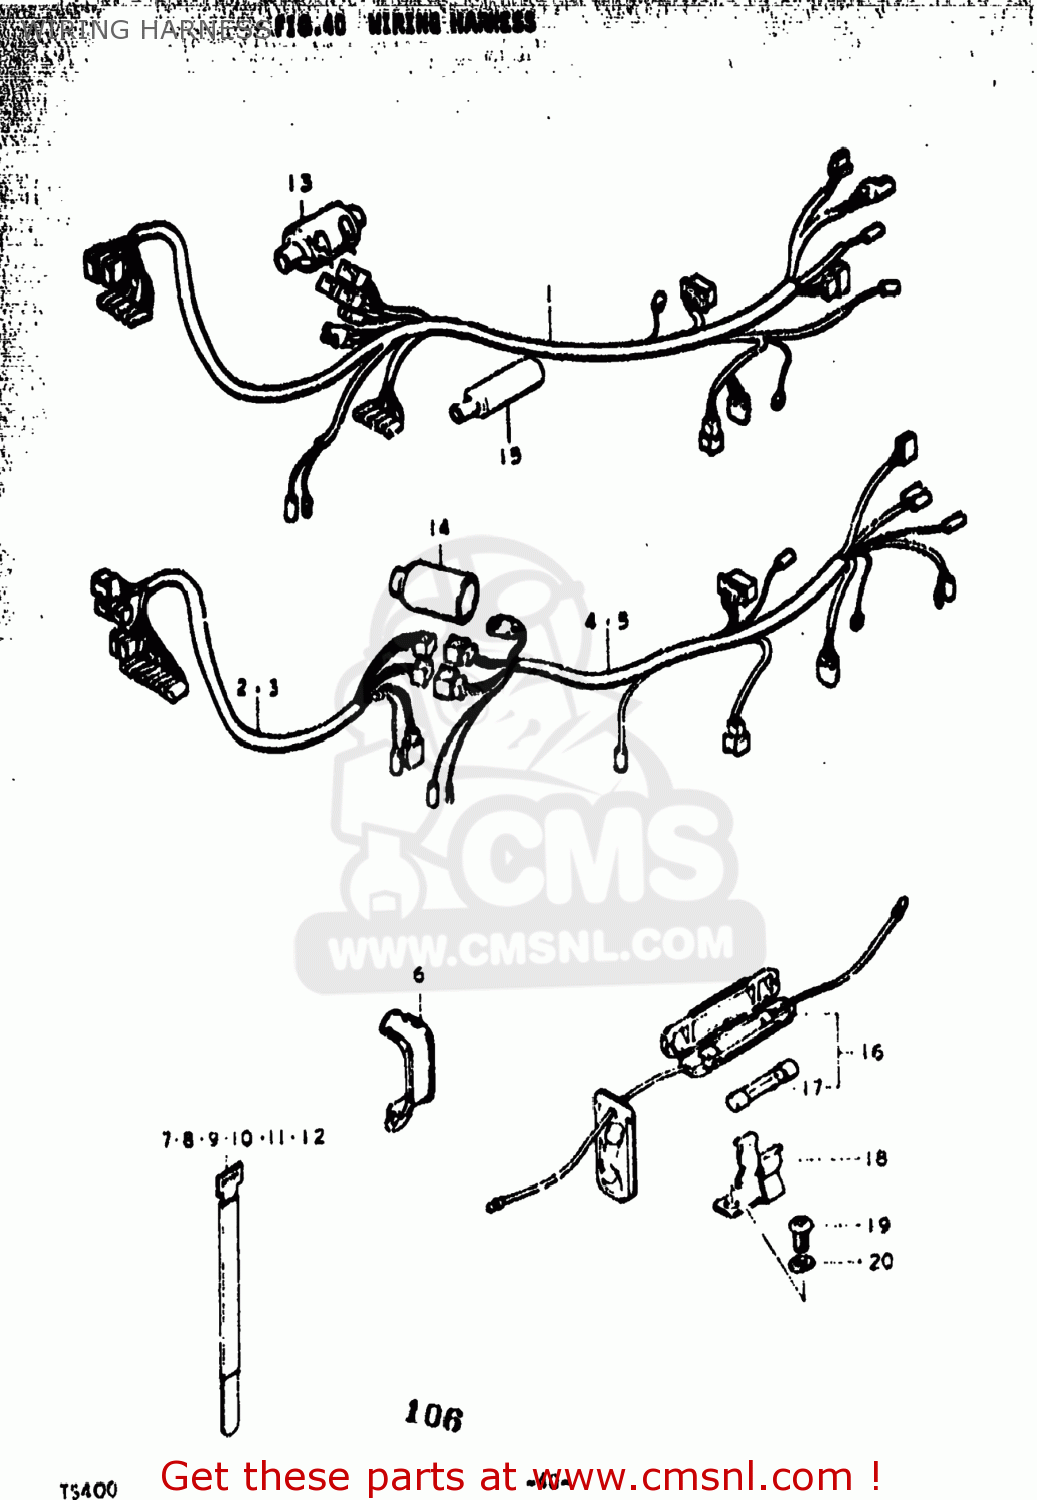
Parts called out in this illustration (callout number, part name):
1	HARNESS,WIRING
2	HARNESS,WIRING
3	HARNESS,WIRING
4	HARNESS,WIRING NO.2
5	HARNESS,WIRING NO.2
6	CLAMP
7	CLAMP(L:250)
8	CLAMP
9	CLAMP
10	CLAMP
11	CLAMP
12	CLAMP
13	BOOT,WIRING HARNESS
14	BOOT,WIRING HARNESS
15	BOOT,WIRING HARNESS
16	BOX ASSEMBLY,FUSE
17	FUSE(15A)
18	HOLDER,FUSE CASE
19	SCREW
20	LOCK WASHER
